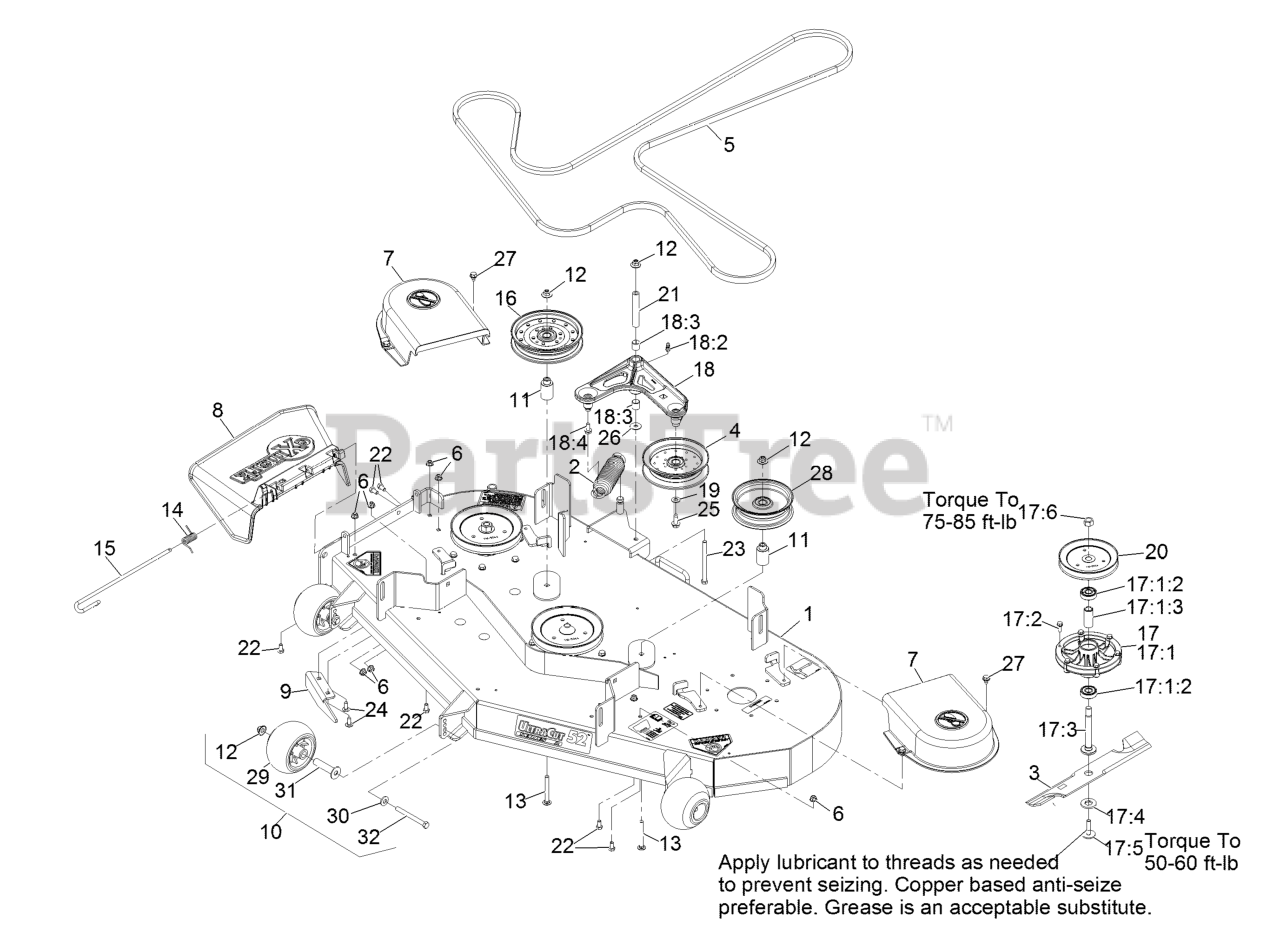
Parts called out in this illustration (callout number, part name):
1	ASM-522 DECK W/DECALS
2	SPRING-EXTENSION
5	BELT-B162.50
6	NUT-HF, NI
7	SHIELD-BELT
8	CHUTE DEFLECTOR XRK M056
9	BAFFLE-DISCHARGE
10	KIT, ANTI-SCALP ROLLER
11	BUSHING-IDLER
12	Nut-Nyloc 3/8-16 Flg
13	BOLT-CARRIAGE
14	SPRING-TORSION
15	PIN-CHUTE
17	CUTTER HOUSING ASM
17:1	HOUSING-CUTTER
17:1:2	BEARING
17:1:3	SPACER-BEARING
17:2	SCREW-TAPTITE
17:3	SPINDLE-HEX PILOT
17:4	WASHER-BLADE DRIVE
17:5	BOLT-BLADE, SEM
17:6	NUT-HEX
18	IDLER ARM ASM
18:2	FITTING-GREASE, 90 DEG
18:3	SLEEVE-BEARING
18:4	SCREW-THD ROLL, HWH
19	WASHER-FLAT
20	SHEAVE,BLADE DRIVE 6.50
21	BUSHING
22	SCREW-HH
23	SCREW-HH
24	SCREW-CARR
25	SCREW-FORMING, THREAD
28	IDLER-PULLEY, FLAT
29	ROLLER-SCALP, ANTI
30	WASHER-BELLEVILLE
31	AXLE, ROLLER
32	SCREW-HH 3/8-16 X 3 3/4 GR 8
